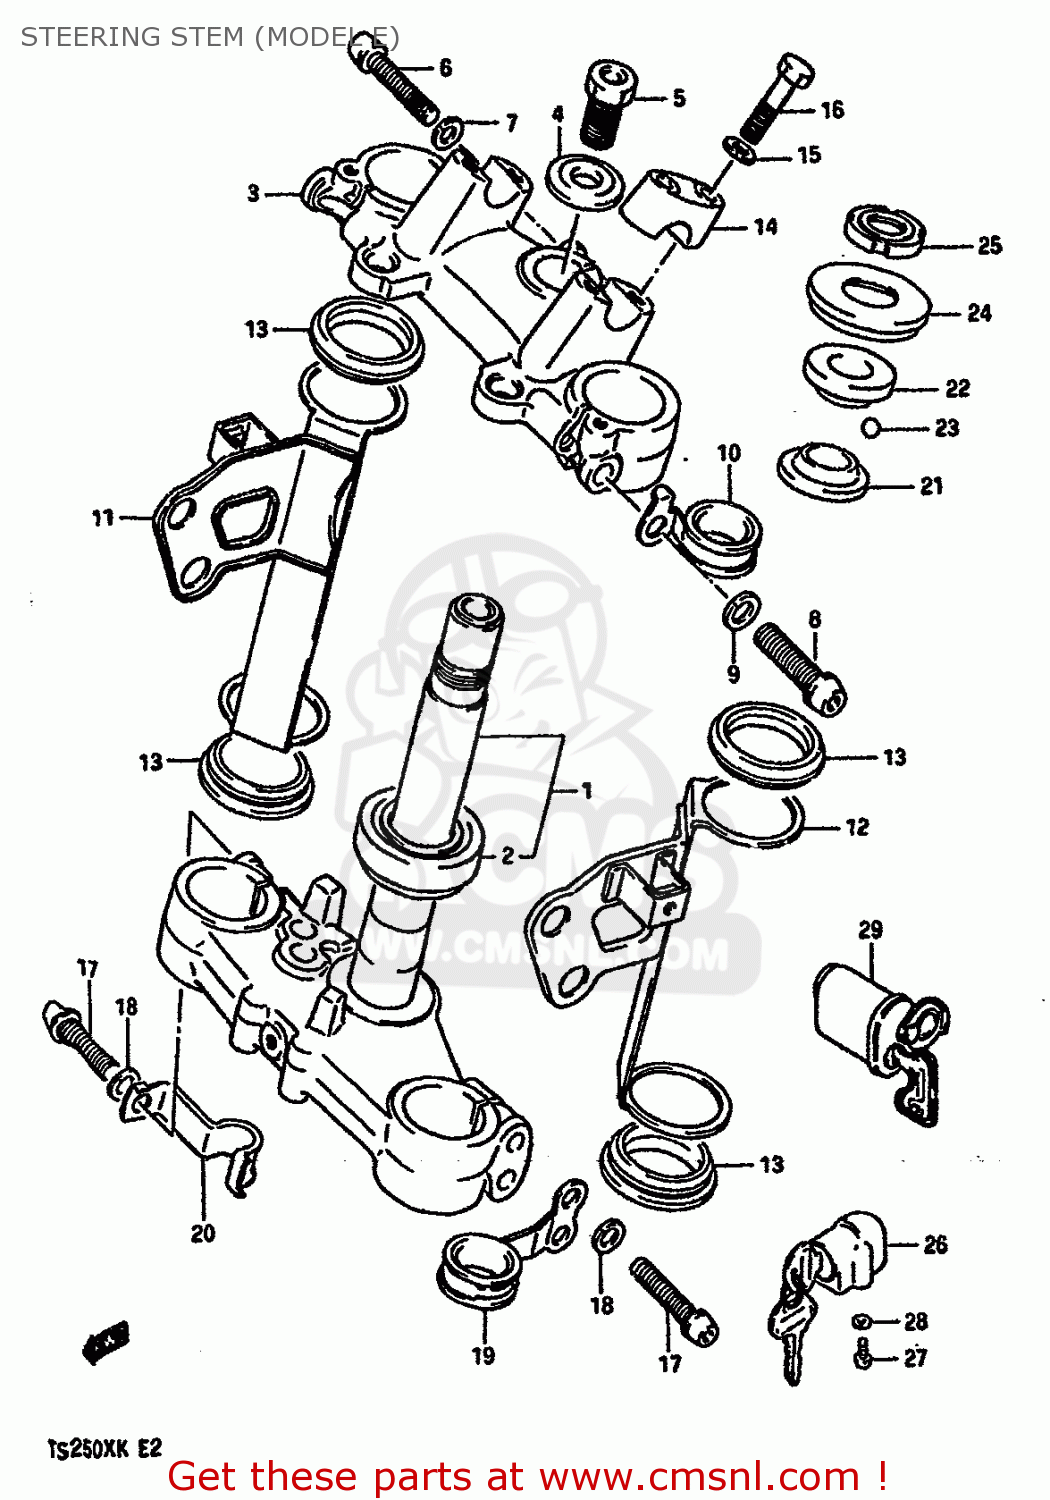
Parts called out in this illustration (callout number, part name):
1	STEM,STEERING
2	BEARING
3	HEAD,STEERING STEM
4	WASHER
5	BOLT
6	BOLT
7	LOCK WASHER
8	BOLT
9	LOCK WASHER
10	CLIP
11	BRACKET,HEADLAMP RH
12	BRACKET,HEADLAMP LH
13	GASKET
14	HOLDER,HANDLEBAR
15	WASHER,LOCK,8.
16	BOLT
17	BOLT
18	LOCK WASHER
19	CLIP
20	GUIDE,CABLE
21	RACE,STEERING INNER (SUJ)
22	RACE,STEERING,OUTER,UPPER
23	BALL
24	SEAL,STEERING UPR DUST
25	NUT,STEERING STEM
26	LOCK ASSY,STEERING
27	SCREW
28	LOCK WASHER
29	LOCK ASSY, STEERING (NEIMAN TYPE EXECUTE
